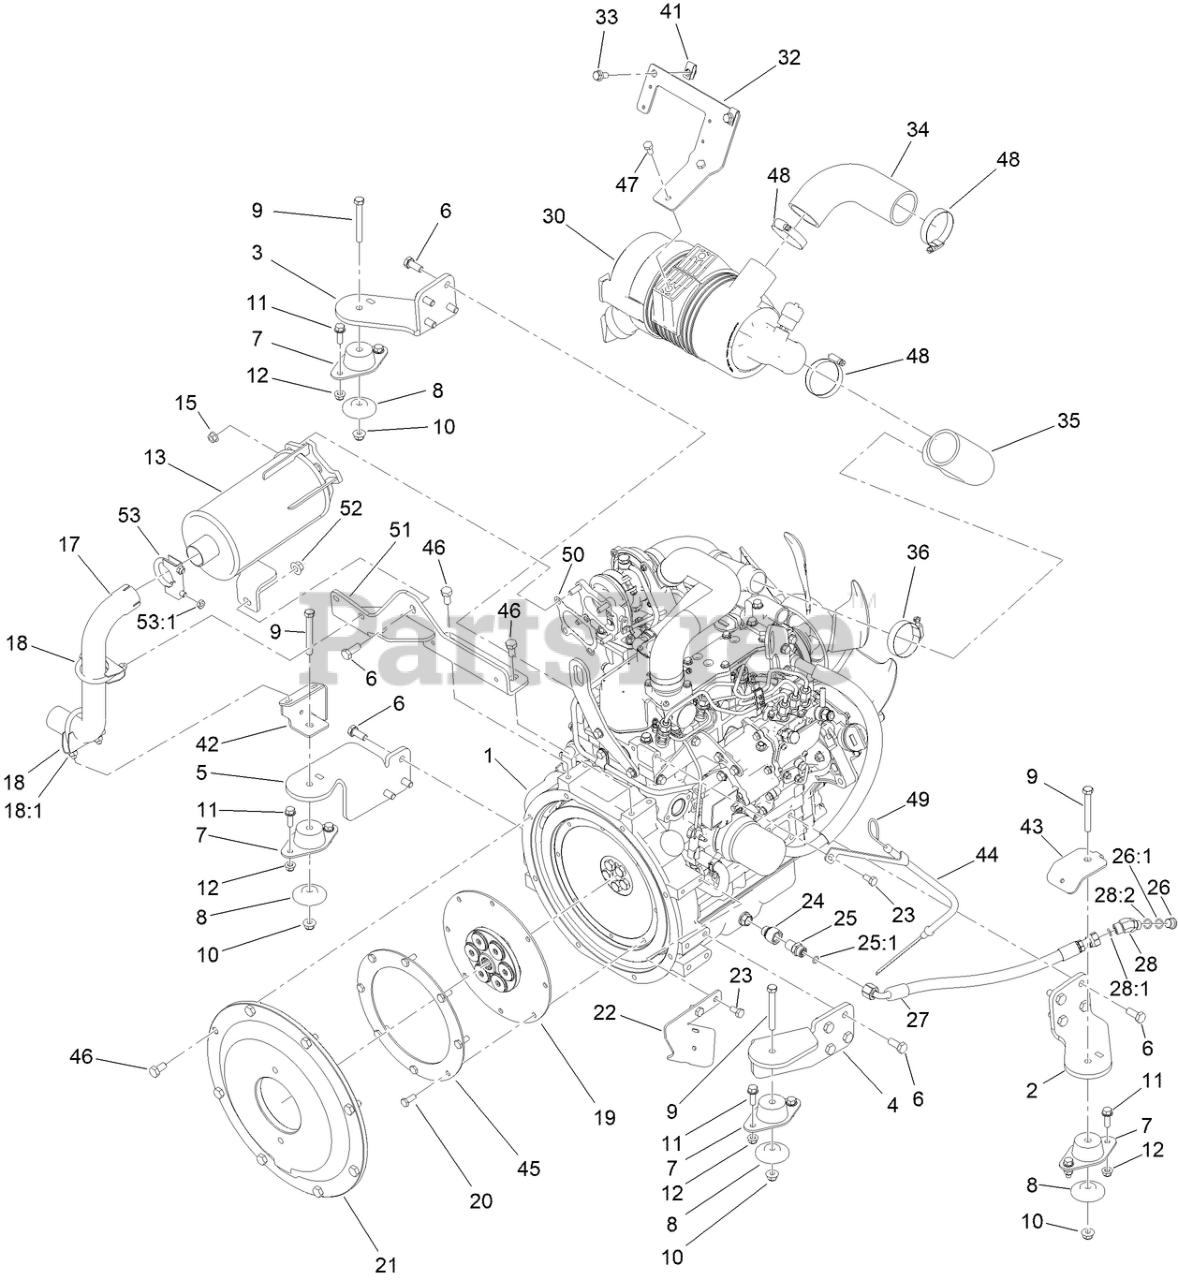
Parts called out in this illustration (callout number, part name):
1	ENGINE-YANMAR, 3TNV80FT-ZMTR2
2	MOUNT-ENGINE, LH, REAR
3	MOUNT-ENGINE, RH, REAR
4	MOUNT-ENGINE, LH, FRONT
5	MOUNT-ENGINE, RH, FRONT
6	SCREW-HH
7	MOUNT-ENGINE
8	SUPPORT-ISOLATOR
9	SCREW-HH
10	NUT-HF, NI
11	SCREW-HHF
12	NUT-HF, NI
13	MUFFLER ASM
15	NUT-HF
17	PIPE-EXHAUST
18	CLAMP-MUFFLER
18:1	NUT-JAM
19	COUPLER-FLYWHEEL
20	SCREW-HH
21	COVER-FLYWHEEL
22	BRACKET-GUIDE, HOSE
23	SCREW-HH
24	ADAPTOR-STR
25	FITTING-STRAIGHT
25:1	O-RING
26	PLUG-HEX, HOLLOW
26:1	O-RING
27	HYD HOSE ASM
28	FITTING-ELBOW, 45 DEG
28:1	O-RING
28:2	O-RING
30	AIR CLEANER ASM
32	BRACKET-AIR CLEANER
33	SCREW-HHF
34	HOSE-INTAKE
35	HOSE-INTAKE
36	CLAMP-HOSE
41	NUT-CLIP, U
42	BRACKET-TAILPIPE, FOOT
43	BRACKET-HOSE GUIDE
44	DIPSTICK
45	RING-FLYWHEEL
46	SCREW-HH
47	SCREW-HH
48	CLAMP-HOSE
49	DIPSTICK
50	GASKET-EXHAUST
51	BRACKET-MUFFLER
52	NUT-LOCK
53	CLAMP
53:1	NUT-HF
